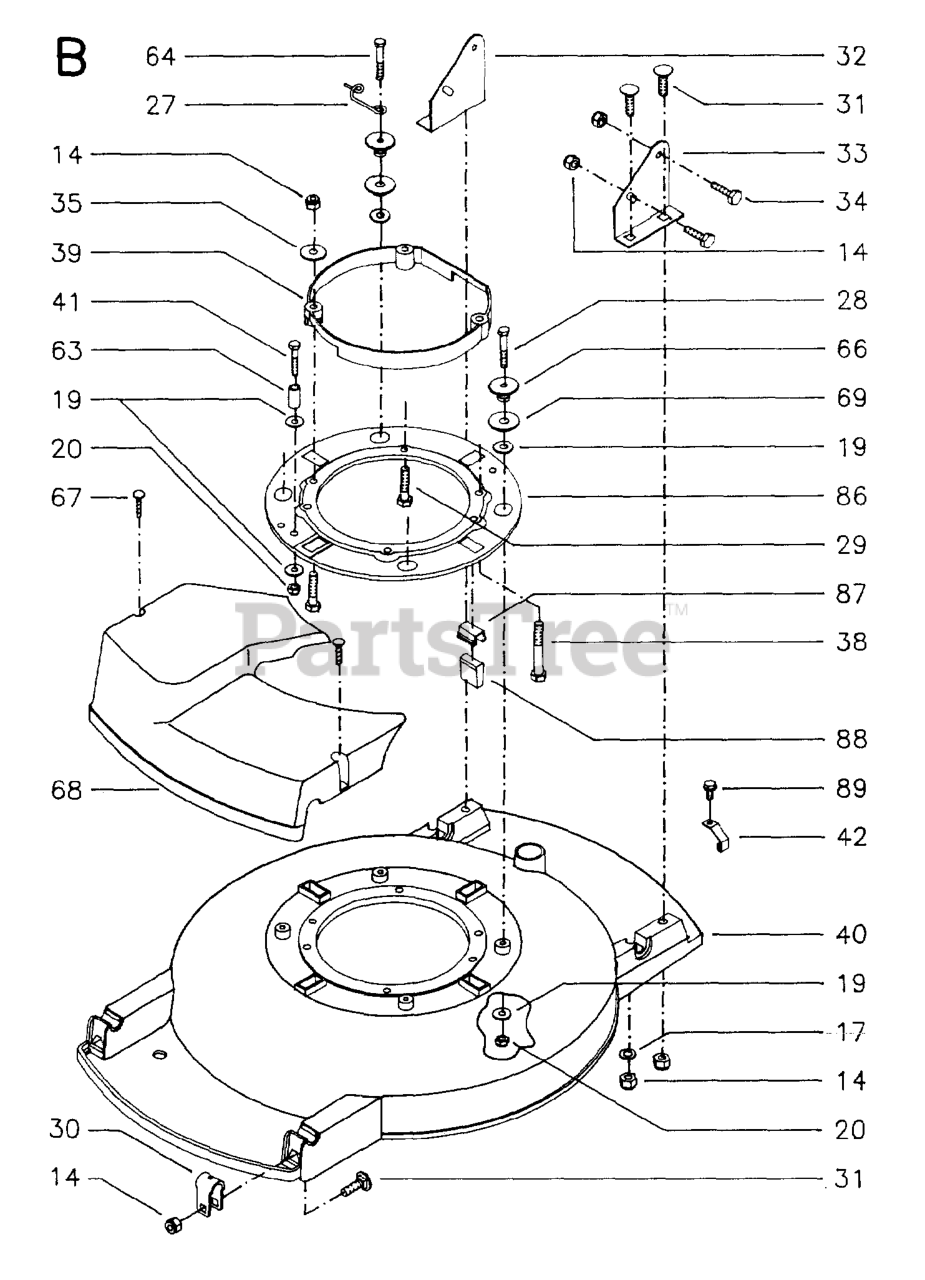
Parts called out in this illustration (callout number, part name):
14	LOCKNUT M8
17	WASHER - 15X7.3X1.6
20	LOCKNUT M6
30	BEARING HOLDER
32	HANDLE BRACKET
33	HANDLE BRACKET
34	BOLT - M8X16
41	BOLT FLANGE
69	RUBBER PIECE
88	DAMPER
